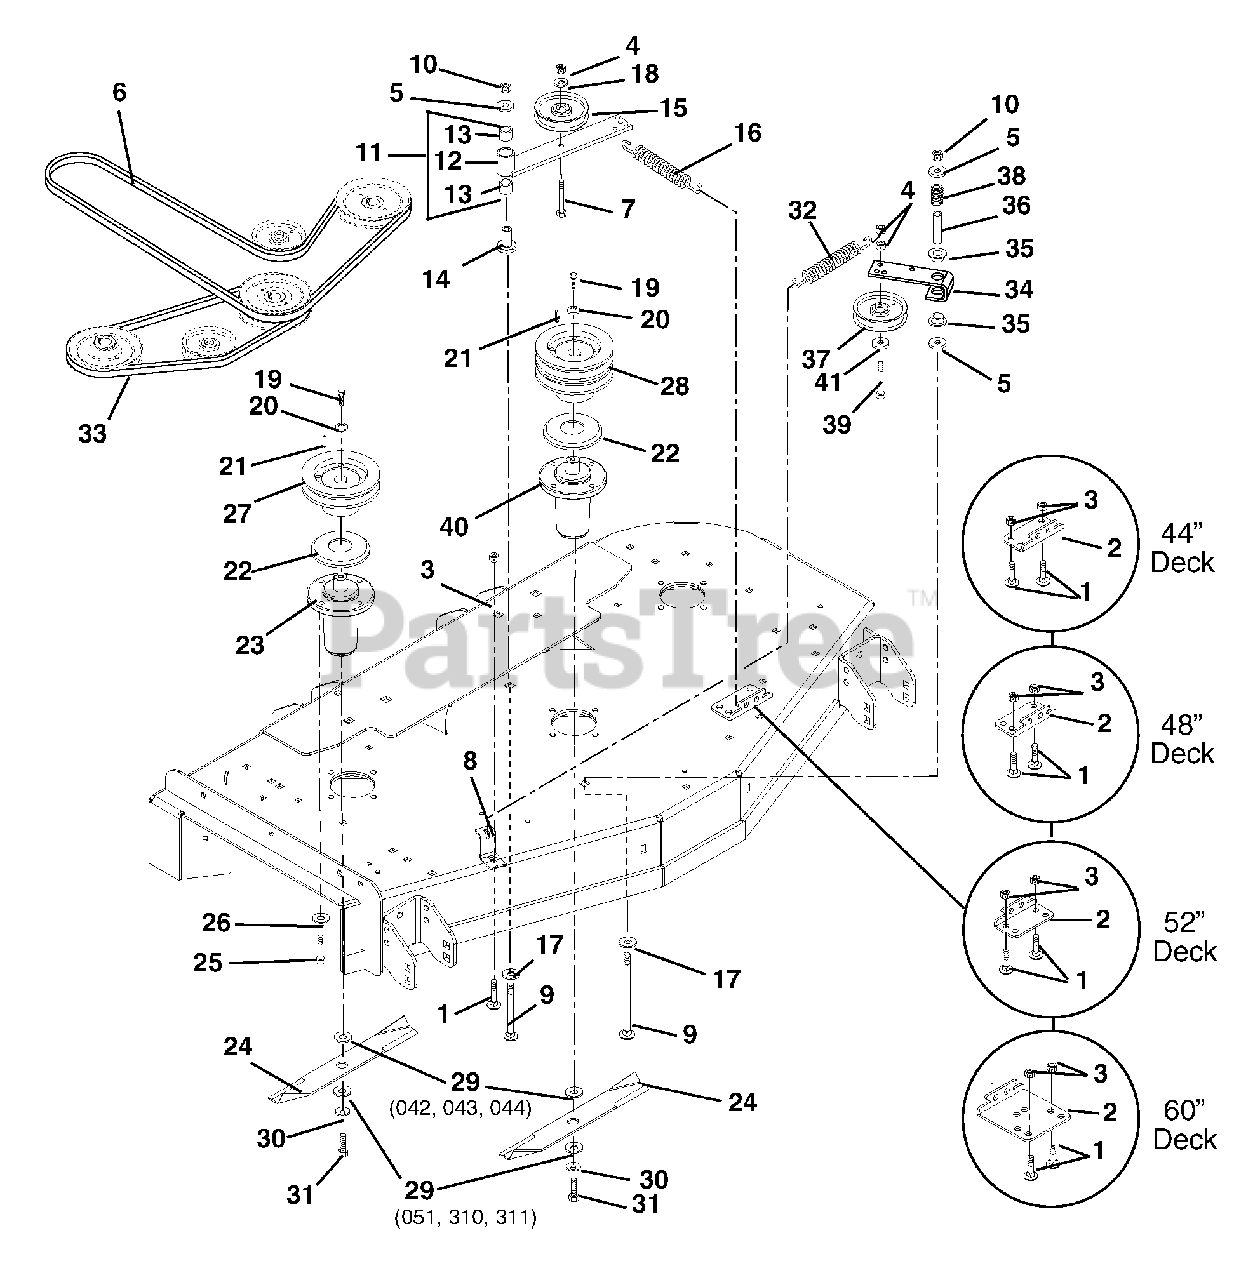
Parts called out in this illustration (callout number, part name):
1	Bolt, Round Head Square Neck .38-16 x .75 Grade 5 (042, 043, 044, 054, 310, 311)
1	Bolt, Round Head Square Neck .38-16 x 1.25 Grade 2 (051, 055)
2	Bracket, Spring (042, 043, 044, 054, 310, 311)
2	Bracket, Spring (051, 055)
3	Nut, Locking Top Flange .38-16
4	Nut, Locking Center .38-16
5	Washer, Flat Steel .531 x 1.25 x .10
6	V-Belt, B-Section 51.50 x .625 (042, 044, 054, 310)
6	V-Belt, B-Section 55.75 x .625 (051, 055)
6	V-Belt, B-Section 48.80 x .625 (043, 311)
7	Bolt, Hex .38-16 x 2.75 Grade 5
8	Anchor, Spring
9	Bolt, Round Head Square
10	Nut, Locking Top Flange .50-13
11	Assembly, Idler Pivot Arm
12	Weldment, Idler Pivot Arm
13	Bearing, 1.00 x 1.12 x .75
14	Bearing, Pedestal
15	Idler, Flat 4.00 x .38 (2.00 W)
16	Spring, External
17	Washer, Flat Steel .755 x 1.375 x .062
18	Washer, Flat Steel
19	Bolt, Hex .38-16 x 1.00 Grade 8
20	Washer, Cupped Serrated .375
21	Key, Straight .25 x 1.00 x .25
22	Slinger, Dust
23	Assembly, Maintenance
24	Blade, Mower (18.00) (044, 054)
24	Blade, Mower 60" (051, 055)
24	Blade, Mower (042, 043)
24	Blade, Mulching
24	Blade, Mower 60" Tungsten
24	Blade, 32" (16.25) (310, 311)
24	Blade, Mulching (042, 043)
25	Bolt, Hex .38-16 x 1.00 Grade 5
26	Washer, Locking
27	Weldment, Spindle Sheave 5.00
27	Weldment, Spindle
28	Sheave, Double (5.25) (042,
28	Sheave, Double
29	Washer, Flat .64 x 1.81 x .250
30	Washer, Bellville
31	Bolt, Hex .62-18 x 1.75 Grade 8
32	Spring, Extension
33	V-Belt, 5L-Section 49.97 x
33	V-Belt, B-Section 19.10
33	V-Belt, B-Section 23.94
34	Arm, Idler Pivot
35	Bushing, Flange .762 x
36	Spacer .56 x .75 x 2.44 Steel
37	V-Idler, 4.00 x .38
38	Spring, Compression
39	Bolt, Hex .38-16 x 2.25 Grade 5
40	Spindle Assembly (Center)
41	Washer, Flat Steel
